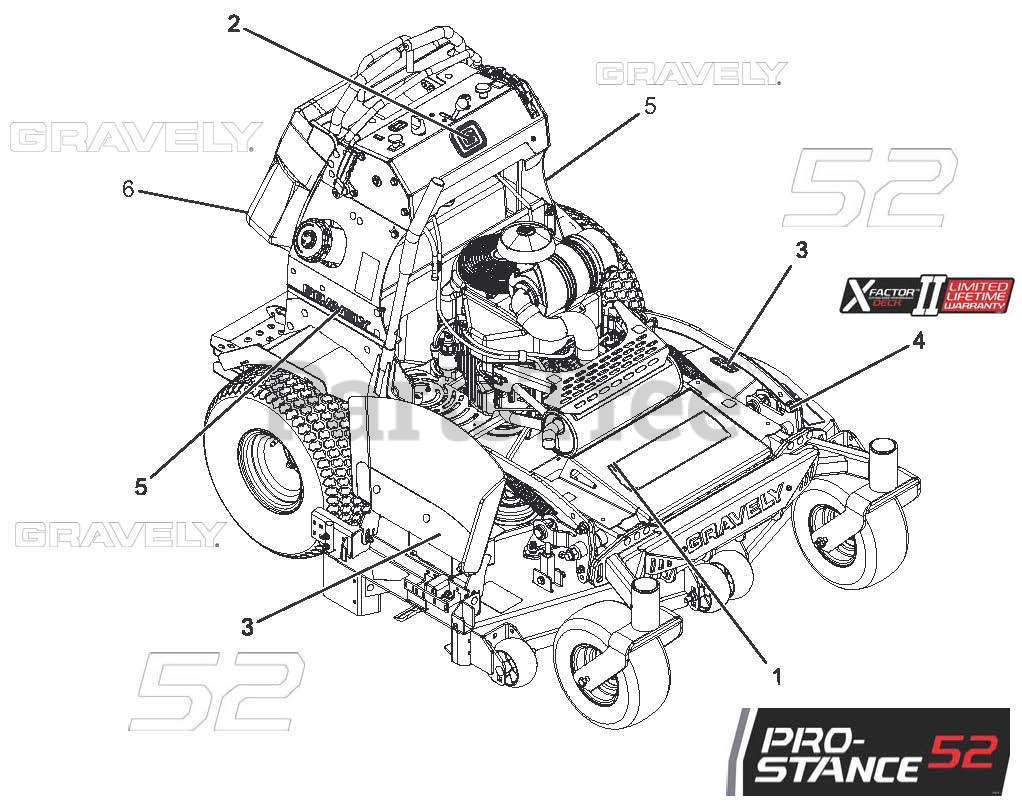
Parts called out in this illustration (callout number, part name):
1	DECAL, PROSTANCE 52
2	DECAL, GRAVELY BRAND
3	DECAL, 52"
4	DECAL, X-FACTOR DECK
5	DECAL, 9.5" GRAVELY LOGO
6	DECAL, 13.5" GRAVELY LOGO
